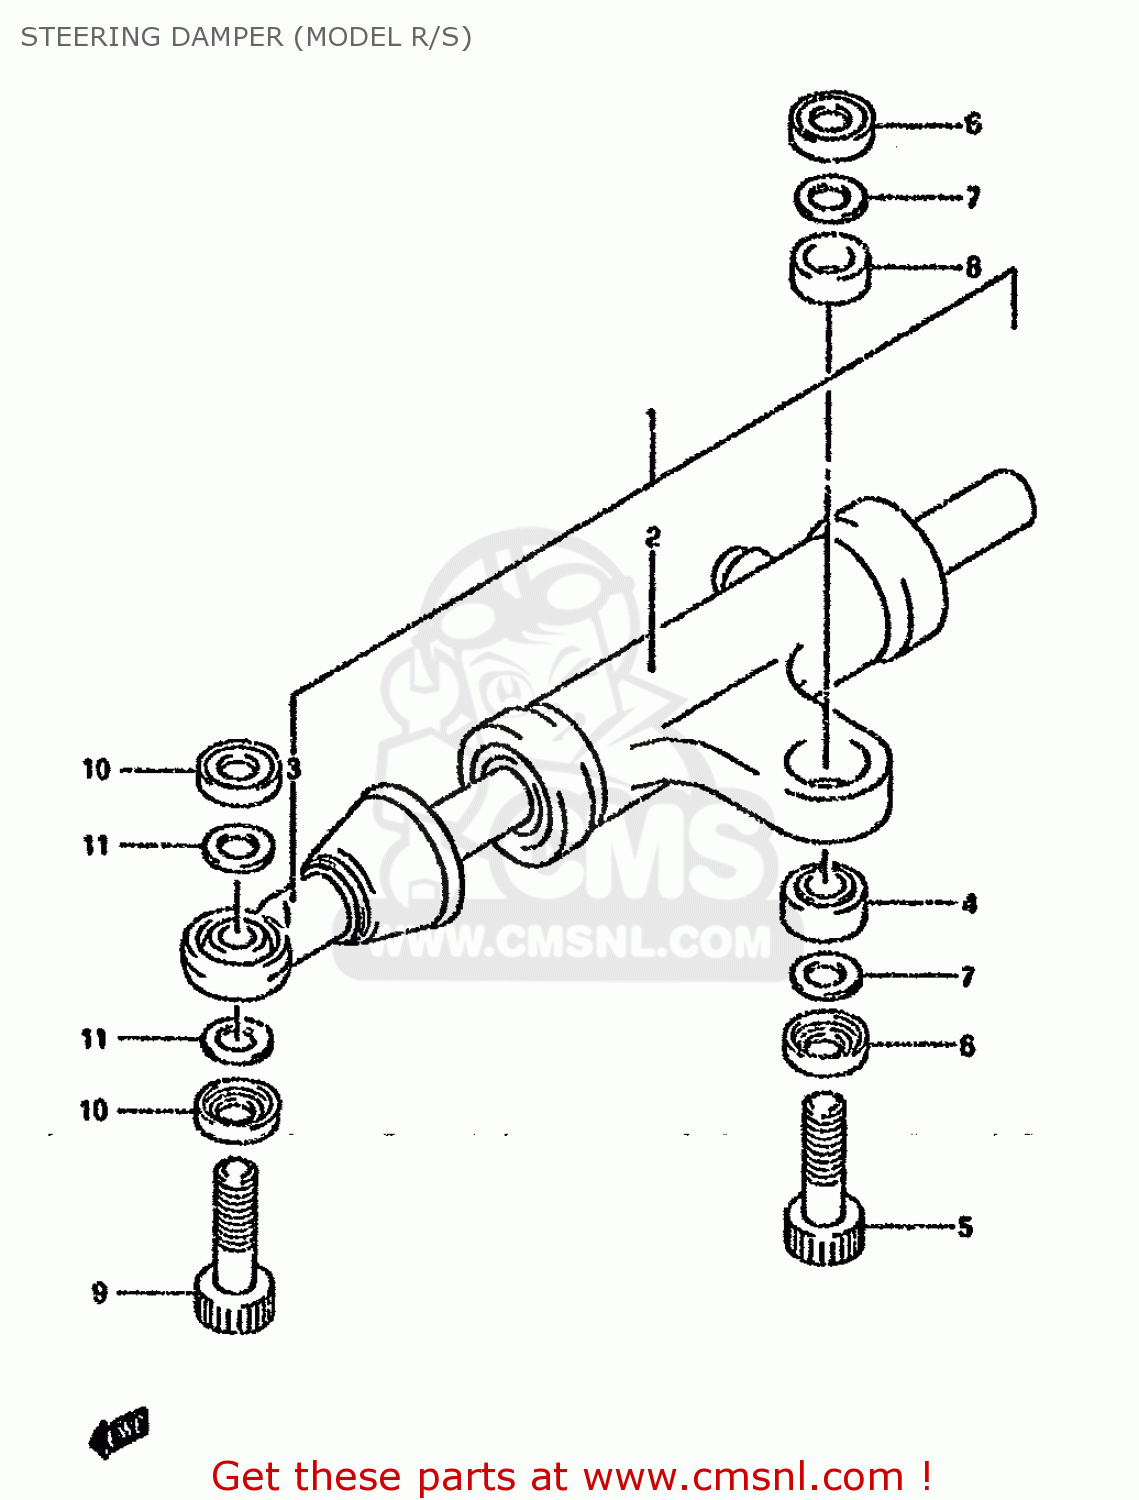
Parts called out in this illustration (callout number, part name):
1	DAMPER ASSY,STEERING
2	DAMPER,STEERING
3	PILLOW BALL,ROD END
4	BEARING(8X17.5X11)
5	BOLT
6	7
7	SHIM
8	SPACER (8.4X14X6)
9	BOLT
10	11
11	SHIM
13	14
14	SHIM
15	BOSS,STEERING DAMPER
16	BOLT 6X20
